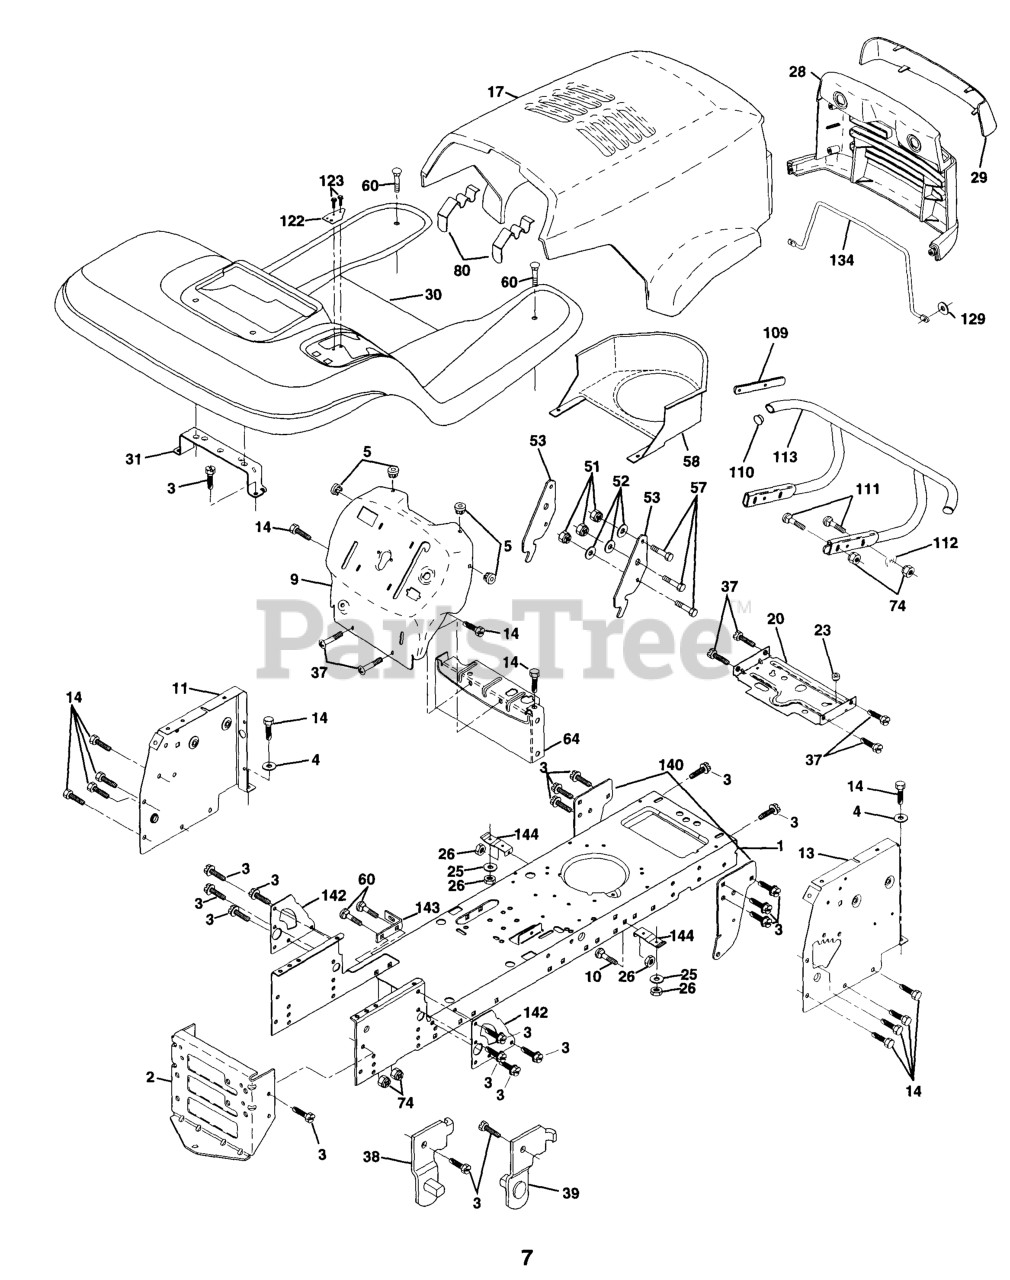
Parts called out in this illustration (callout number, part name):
1	CHASSIS WELDMENT
2	STRETCH DRAWBAR
3	SCREW
4	Washer 13/32 x 3/4 x 16 Ga.
5	DASH PANEL
9	DASH PANEL
10	BOLT D
11	PANEL DASH LH
14	SCREW LT
17	HOOD - LT/YT
20	PLATE MTG
23	BUSHING.SNAP.NYL.BLK.
25	WASHER
26	NUT
28	GRILLE LT/PL HUSQVARNA
29	LENS LT/PL HUSQVARNA
30	FENDER FOOTREST
31	BRACKET.SUPPORT.FENDER
37	Screw Thdrol 6/16-18 x 1/2 TYT
38	BRACKET LH PIVOT
39	BRACKET RH PIVOT
51	LOCKNUT.NYLOC.1/4-20
52	WASHER
53	BRACKET PNT PICK OFF LT/PL
57	BOLT
58	AIR DUCT P/L/LT
60	Bolt Rdhd Sqnk 3/8-16unc x 3/4
64	DASH LOWER
80	LATCH HOOD
109	BRACKET BUMPER
110	Plug Plastic
111	Belt Rdhd 3/8-16 UNC x 1-1/2
112	WASHER
113	BUMPER ASM
129	WASHER
134	ROD SUPPORT HOOD LT/PL HUSQ
140	BRACKET CHASSIS FRONT
142	PLATE REINFORCEMENT
143	BRACKET, SWAY BAR
144	BRACKET FOOTREST
146	SCREW TORX HD 5/16X18
